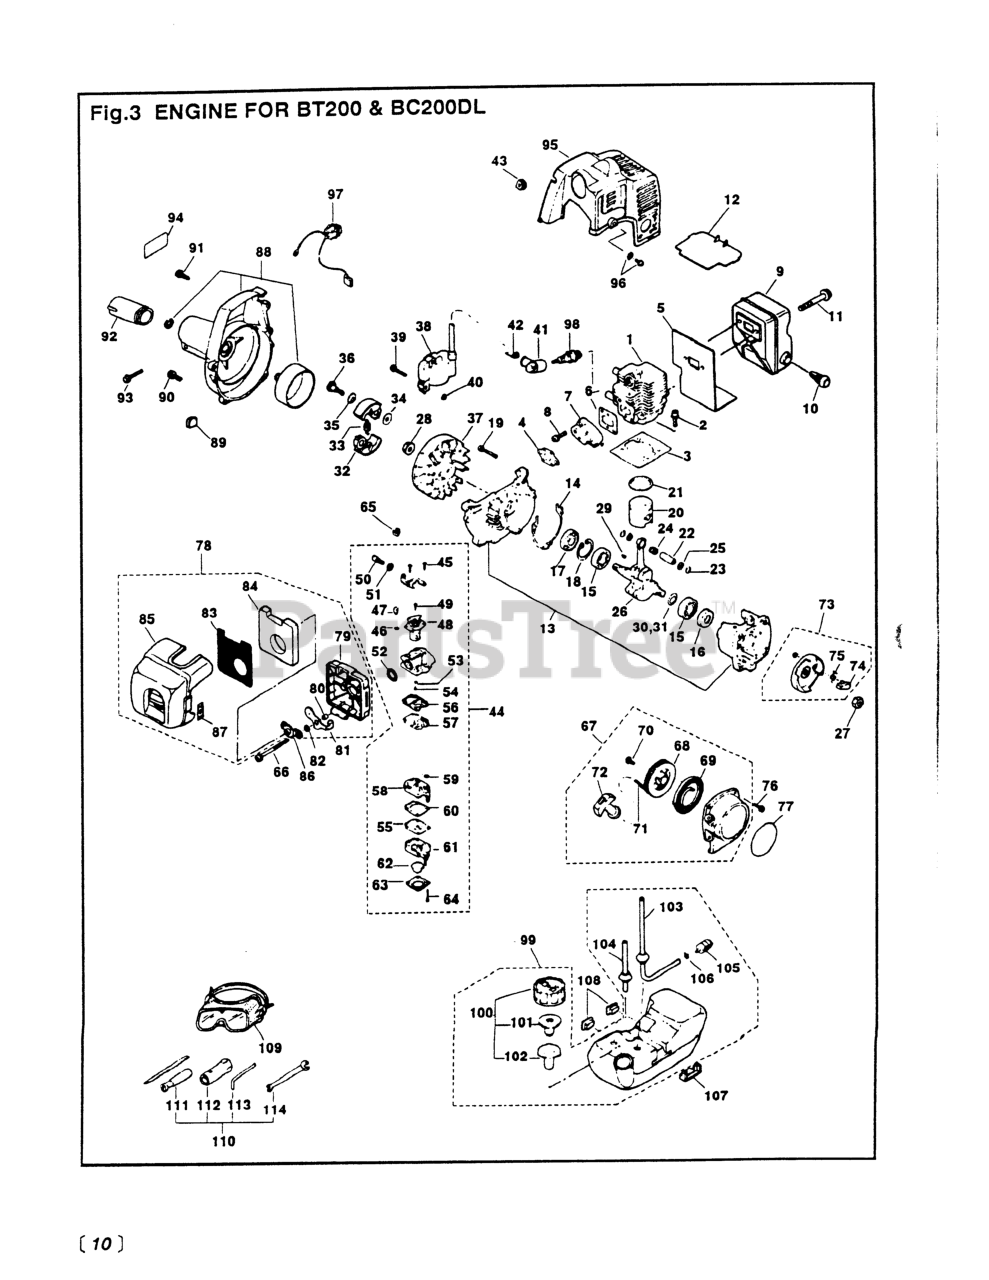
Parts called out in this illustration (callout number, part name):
1	CYLINDER
2	BOLT, M5 X 22
8	SCREW, M5 X 20
10	ARRESTER (RPLS 5850-15140)
11	BOLT(NO LONGER AVAILABLE)
13	CRANKCASE (RPLS -21100)
15	BEARING
17	SEAL, OIL (RPLS 1140-21220)
18	RING, SNAP, M28 x 1.2
19	SCREW, M5 x 30(RPLS 0263-00530
20	PISTON
21	RING, PISTON (RPLS 1850-41210)
22	PIN, PISTON 5x8x26
23	RING, SNAP (RPLS 1101-41320)
25	WASHER
29	KEY
31	SHIM (NO LONGER AVAILABLE)
33	SPRING (NLA)
34	WASHER, FLAT (USE 182303)
35	WASHER (RPLS -51241)
36	BOLT
38	COIL
39	SCREW, M4 X 22
42	SPRING
43	GROMMET
44	CARBURETOR (RPLS. -81003)
45	SCREW
46	RING
47	SWIVEL
48	VALVE ASSEMBLY
50	SCREW, CABLE ADJUSTER
51	NUT, CABLE ADJUSTER
52	RING, PACKING
53	RING, O
55	DIAPHRAGM (USE 4810-81260)
56	GASKET, PUMP
57	DIAPHRAGM
58	BODY, PUMP
60	GASKET, DIAPHRAGM
61	BODY, PURGE
62	PUMP, PRIMING
63	COVER, PUMP
64	SCREW
65	CAP, CABLE END
67	RECOIL
68	REEL
69	SPRING, SPIRAL
70	SCREW (RPLS -75150)
74	RATCHET (RPLS 1850-75220)
75	SPRING, RETURN
76	SCREW, M4 X 16
77	LABEL
78	CLEANER ASSY (RPLS -82000)
79	BODY (RPLS -82110)
80	SLEEVE
81	SHUTTER (RPLS -82131)
83	SCREEN
84	ELEMENT
85	COVER (RPLS -82200)
86	PLATE (RPLS -82320)
87	LABEL
89	GROMMET
90	SCREW, M5 X 20
91	SCREW, HOUSING
93	BOLT, M6x35 (RPLS -50635)
96	SCREW, M5 x 12
100	CAP (USE 5601-85201)
101	VALVE (NO LONGER AVAILABLE)
103	PIPE COMP
105	5500-85400 (RRLS. 1750-85300)
106	CLIP (REPLACES 2841-31280)
107	CUSHION (S)
108	CUSHION (F)
110	TOOL SET
111	SCREWDRIVER
112	SOCKET, HEX, 3/4
113	BAR
114	SPANNER, 8 X 10 (RPLS 2540- )
